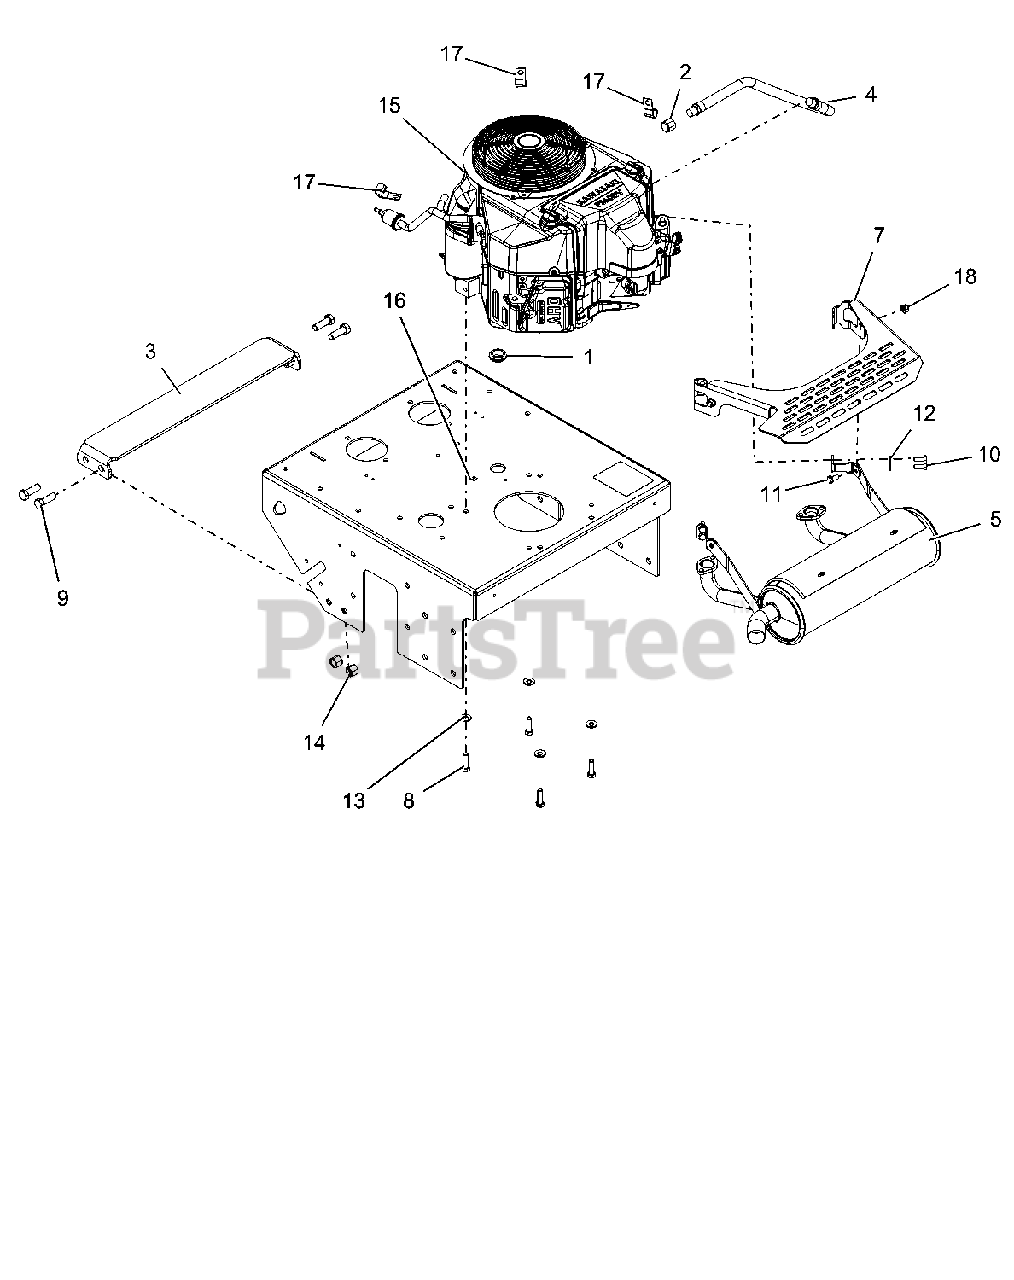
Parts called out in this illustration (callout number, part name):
1	GROMMET:RUB:.88IDx1.38ODX.14GR
2	PIPE, CAP 3/8 NPT FEMALE
3	PLATE, ENGINE BED REAR 52/48-RED
4	DRAIN, M20 OIL
5	MUFFLER, PROSTANCE
7	SHIELD, MUFFLER-BLACK
8	BLT-HEX .38-16X1.25 GR5 YWZC NYTORQ
9	BLT-HEX .50-13X1.50 GR5 YWZC
10	@BLT-HEX M8-1.25X20 YWZC
11	SCR - HEX -FL M8X1.25X16 10.9
12	WSHR-LK .31X.078 REG YWZC
13	WSHR, 3/8" SPRING DISC
14	NUT-LK-NYL .50-13 YWZC
15	ENGINE, KAWASAKI FS691
16	ASSM, 48-52" FRAME W/DECALS
17	P-CLIP, .500 INSULATED
18	LOCKNUT, M8 X 1.25, FLANGED ZN
